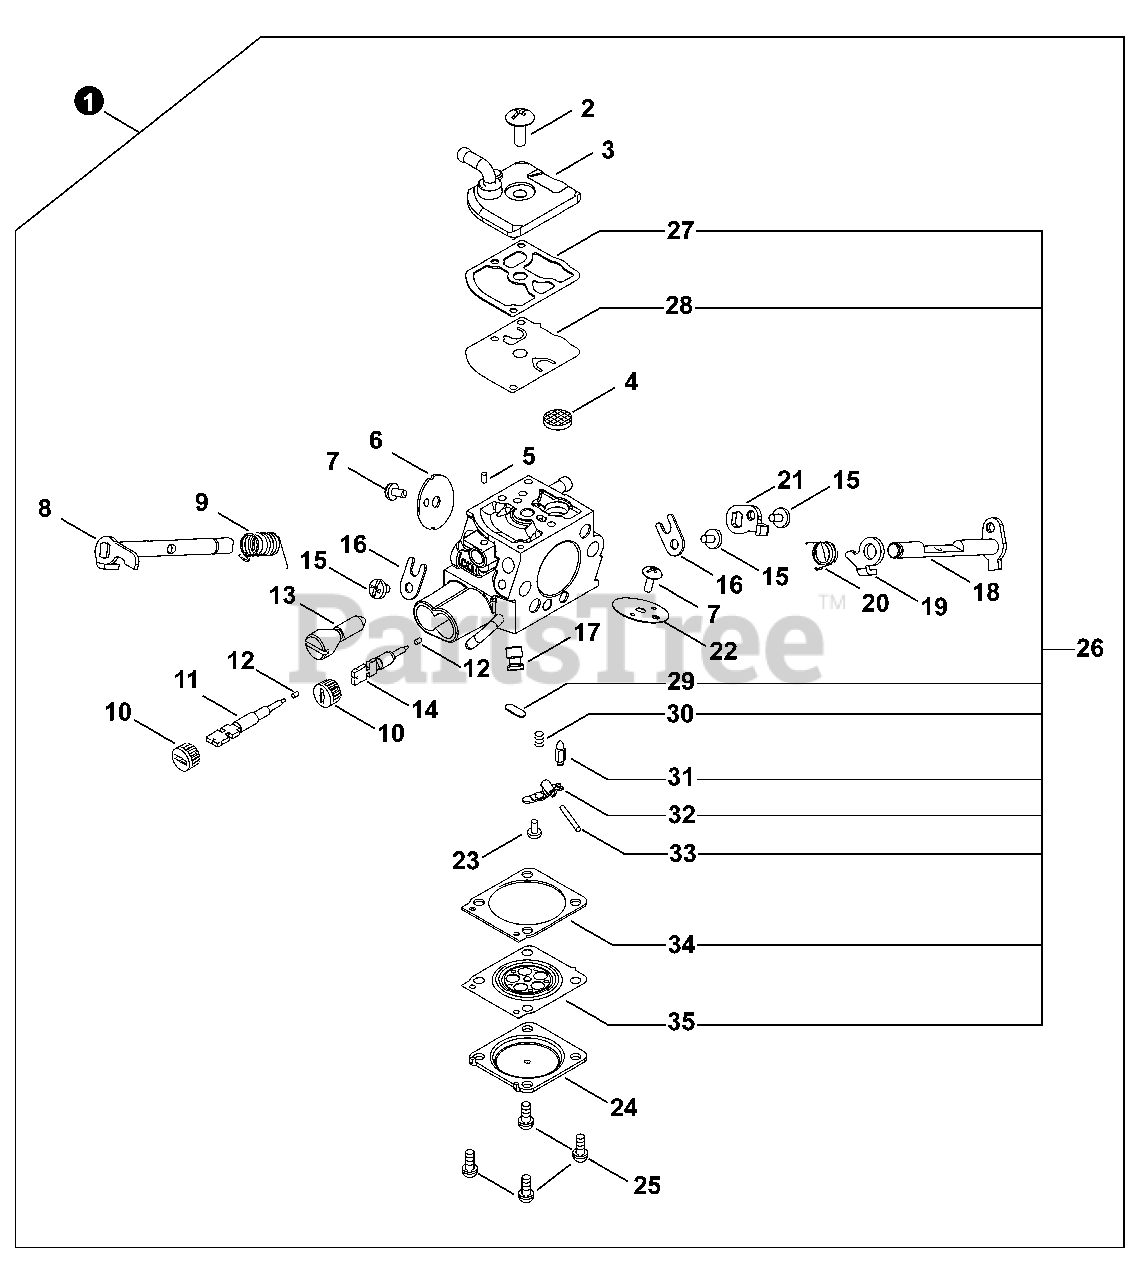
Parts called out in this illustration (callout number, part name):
1	CARBURETOR - C1Q-110129C
3	COVER, PUMP
4	SCREEN, FUEL INLET
5	PIECE, FRICTION
6	VALVE, THROTTLE
7	SCREW 3×4.5
8	SHAFT ASSY, THROTTLE
9	SPRING, RETURN
10	CAP, LIMITER
11	SCREW, IDLE ADJUST
12	RETAINER
13	SCREW, THROTTLE ADJUST
14	SCREW, MAIN ADJUST
16	CLIP, THROTTLE SHAFT
17	NOZZLE, CHECK VALVE
18	SHAFT ASSY, CHOKE
19	LEVER, CHOKE
20	SPRING, RETURN
21	LEVER, THROTTLE
22	VALVE, CHOKE
24	COVER, METERING DIAPHRAGM
26	REPAIR KIT, CARBURETOR
27	GASKET, PUMP
28	DIAPHRAGM, PUMP
29	PLUG, WELCH
30	SPRING, COIL
31	VALVE, INLET NEEDLE
32	LEVER, METERING
33	PIN, METERING LEVER
34	GASKET, METERING DIAPHRAGM
35	DIAPHRAGM, METERING
